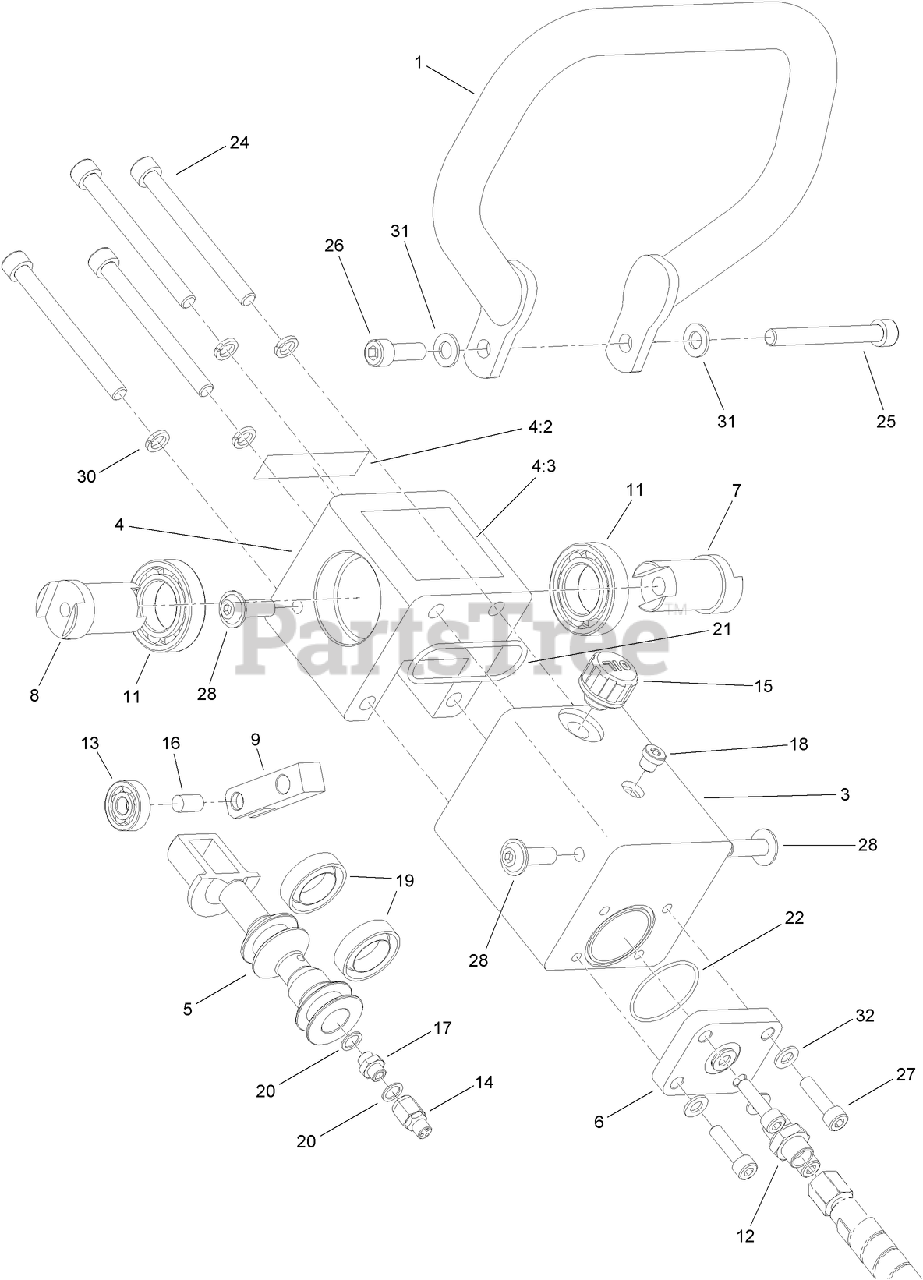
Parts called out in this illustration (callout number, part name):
1	HANDLE
3	BODY-MANIFOLD (I)
4	MANIFOLD ASM
4:2	DECAL-CAUTION
4:3	DECAL-OPERATION
5	PISTION
6	PLATE-SEALING
7	PIVOT I
8	PIVOT I I
11	BEARING
12	SOCKET
13	BEARING
14	VALVE-DIRECT
17	COUPING
19	PACKING
21	O-RING
22	O-RING
30	WASHER
31	WASHER
32	WASHER
